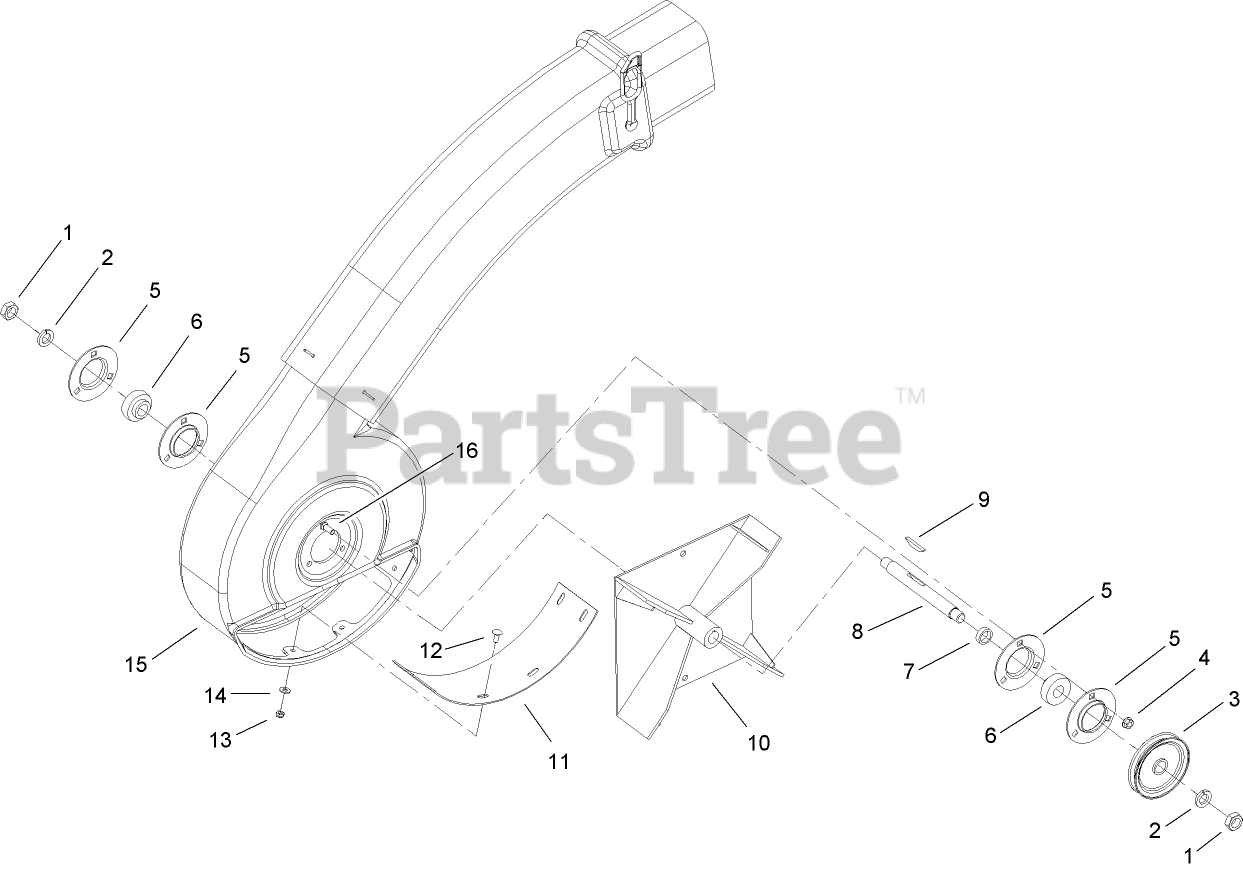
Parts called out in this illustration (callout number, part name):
1	NUT-JAM
2	WASHER-LOCK
3	PULLEY-BLOWER
4	NUT-HF
5	FLANGE
6	BEARING-BALL
7	Spacer
8	SHAFT-BLOWER
10	IMPELLER ASM
11	Cover-Blower, Bottom
12	SCREW-CARR
13	NUT-LOCK, NI
14	WASHER-FLAT
15	BLOWER HOUSING ASM
16	SCREW-CARR
